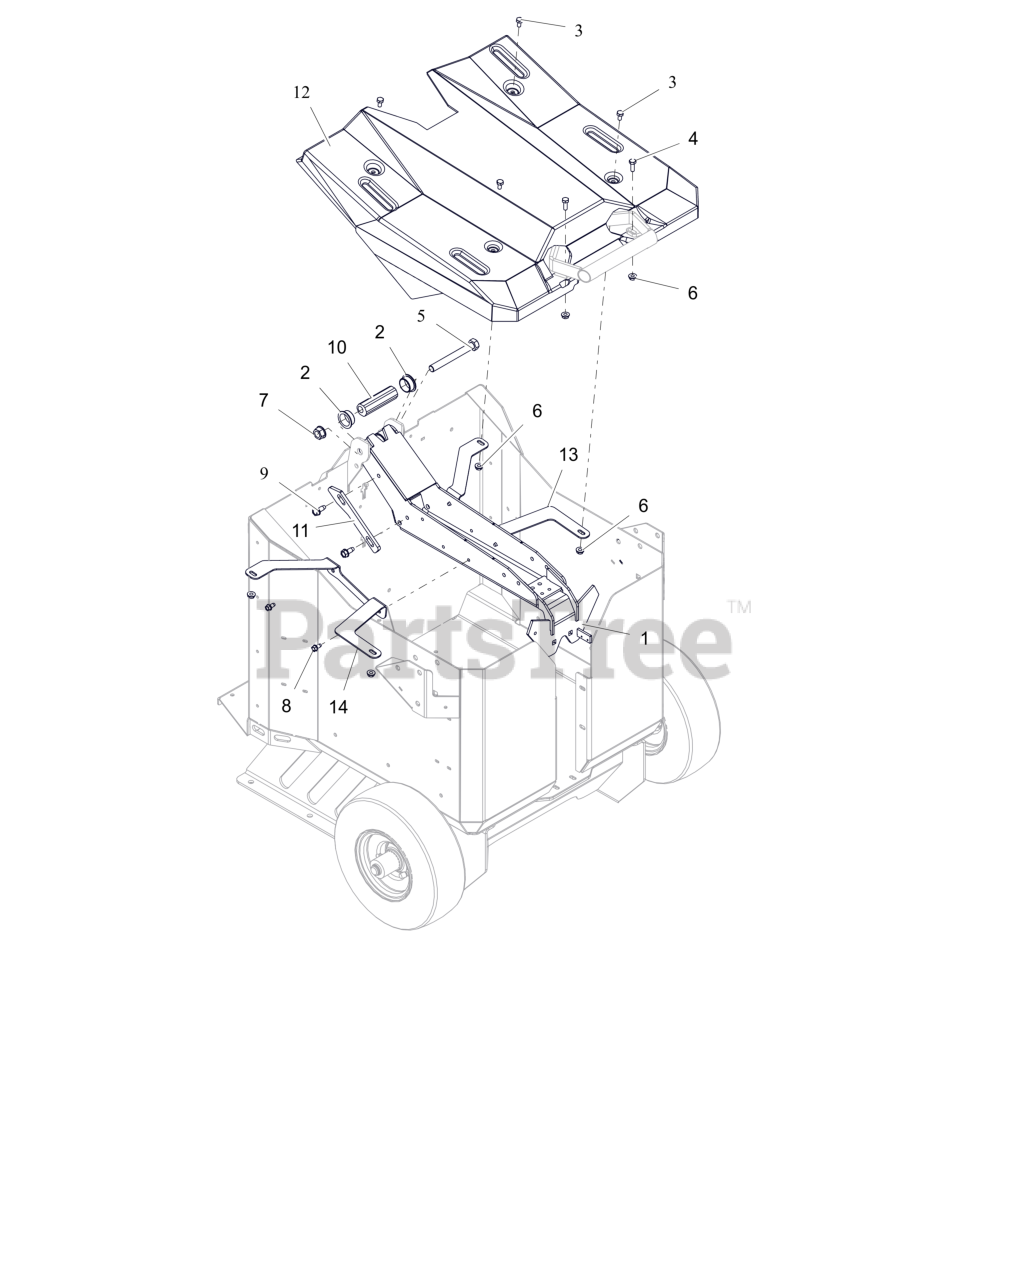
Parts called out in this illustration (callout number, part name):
1	WLDMT, MAIN HOLD DOWN (BLUE)
2	BSHG-FLG 1.0X1.125X.50X1.375 R
3	BLT,HEX .25-20X.50 G5 ZCC
4	BLT, HEX .25-20X.75 G5 ZCC
5	BLT, HEX 0.5-13X4.25 GR5 ZCC
6	NUT-LK-CTR-FLG .25-20 ZC120
7	NUT-LK-CTR-FLG .500-13 GG ZCC
8	SCR-TAP .25-20X.50 HWH ZCC
9	SCR,TAP .312-18X.75 HWH TR ZCC
10	ECCENTRIC, HOOD LATCH-FRONT
11	STOP, HOOD (BLACK)
12	HOOD, OFFBOARD CHARGER
13	PLATE, HOOD MNT (R) (BLACK)
14	PLATE, HOOD MNT (L) (BLACK)
